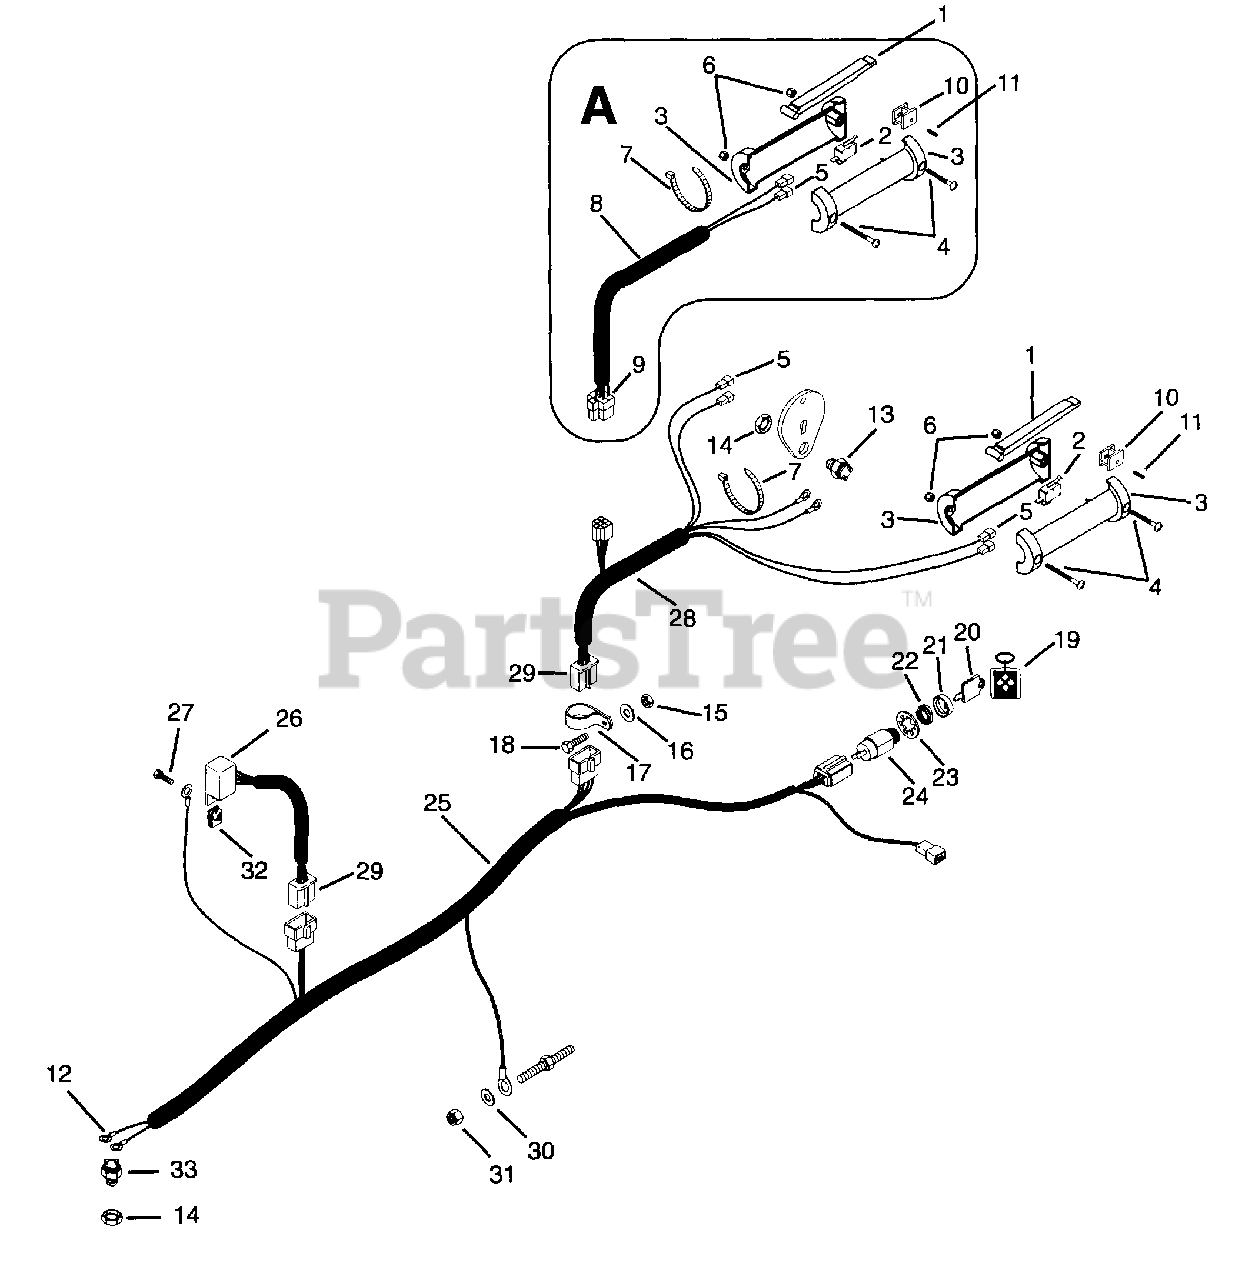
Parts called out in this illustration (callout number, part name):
1	Lever
2	Switch
3	Handle, Left Hand & Right Hand
4	Screw-Machine 10-24 x 1.50
5	Terminal, Female
6	Nut-Locking-Nylon 10-24
7	Tie Wrap, Black
8	Harness, Steering Brake
9	Connector
10	Holder, Switch
11	Pin-Roll .094 x .750
12	Terminal, Eyelet
13	Switch, Interlock Closed
14	Nut-Stamped .56-18
15	Nut-Locking-Center .250-20 Grade 2
16	Washer-Flat-Steel .281 x .620 x .065
17	Cable Clamp
18	Bolt-Hex .25-20 x .75 Grade 5
19	Key Chain
20	Ignition Switch Key
21	Cap-Ignition Switch
22	Nut-Panel .625-32
23	Washer-Lock Internal .625 x .045
24	Switch Assembly
25	Harness, 8 & 12-HP Recoil
26	Module
27	Bolt-Hex .25-20 x .63
28	Harness, Wiring Handlebar
29	Terminal
30	Washer-Flat-Steel .459 x .938 x .065
31	Nut-Locking-Center .375-16 Grade 2
32	Nut-Speed .25-20
33	Switch, Interlock Open
